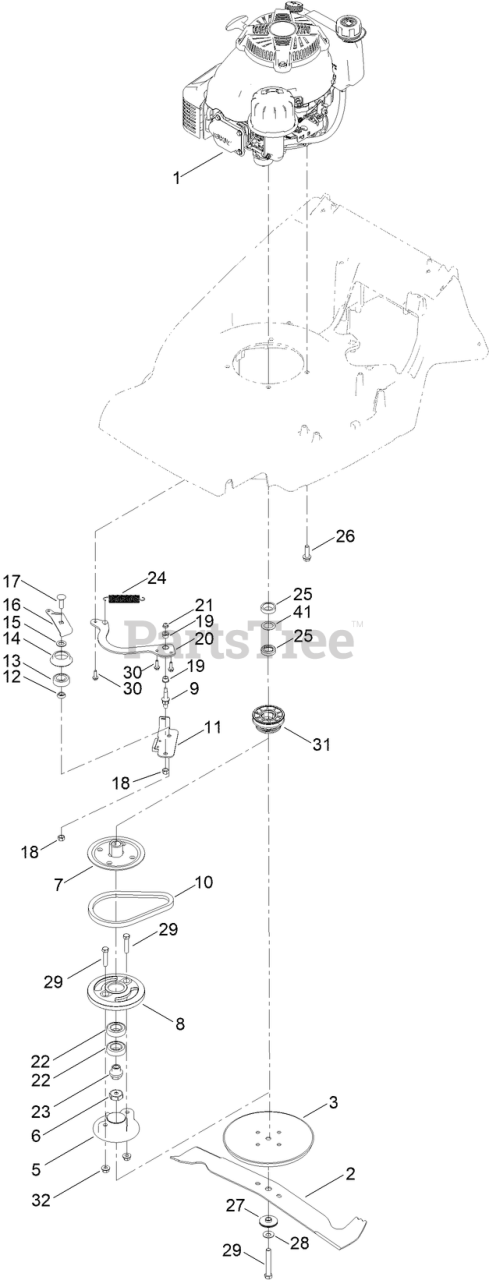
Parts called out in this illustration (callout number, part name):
1	ENGINE-KAWASAKI, FJ180V, BBC
1	CRANKSHAFT KIT, KAWASAKI FJ180BBC
2	CUTTERBAR
3	DISC-FRICTION
5	SPACER-BLADE, BBC
6	NUT-RETAINING
7	PULLEY HALF DRIVE BBC
8	DRUM-BBC
9	BOLT-SHOULDER
10	BELT
11	PLATE-BRAKE
12	SPACER-BEARING
13	BEARING-BALL
14	RETAINER-BELT
15	SPACER
16	PLATE-TENSIONER
17	SCREW-CARR
18	LOCKNUT
19	BUSHING-FLANGE
20	BBC ANCHOR PLATE ASSY
21	NUT-HF
22	BEARING
23	BBC SHAFT NUT
24	SPRING-TENSION, BRAKE
25	SPACER-RETAINING
26	SCREW-TAPTITE, UNC
27	SPACER-DISTANCE, CUTTERBAR
28	WASHER-LOCK
29	BOLT, UNF 3/8 X 1.3/4 (GRADE 8. ROHS)
30	SCREW-TAPTITE
31	PULLEY-ENGINE
32	NUT-FLANGE, LOCK
41	SPRING-DISK
